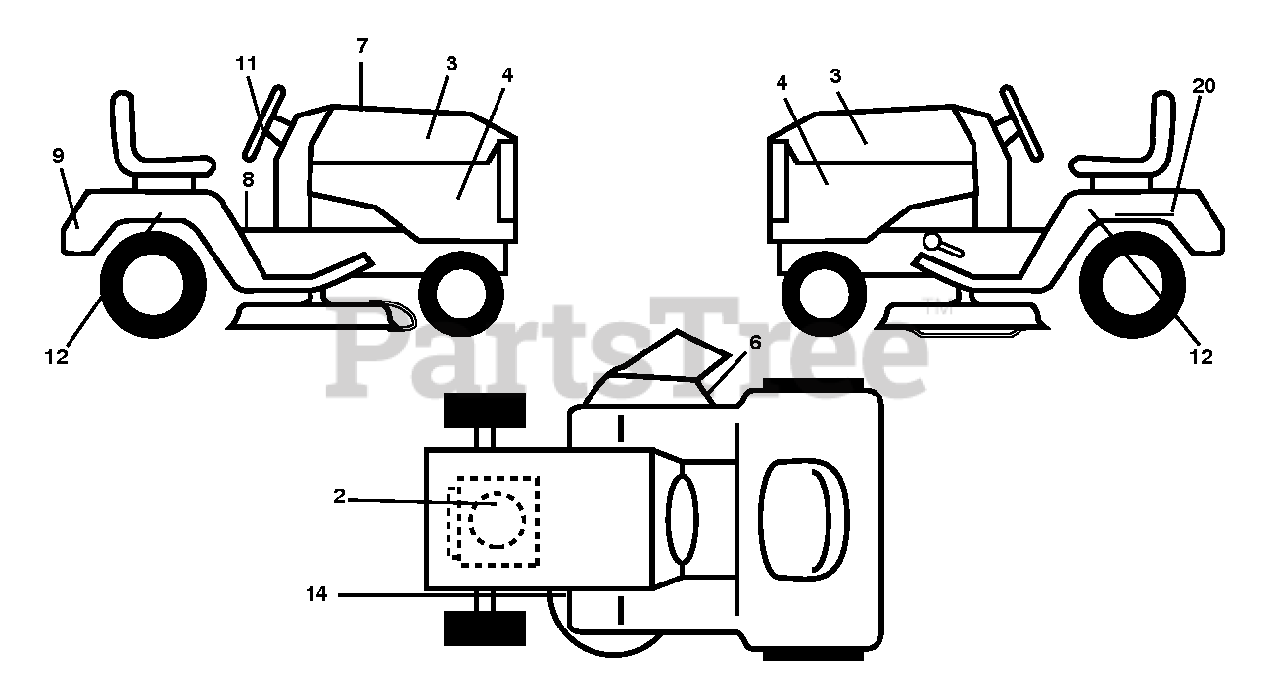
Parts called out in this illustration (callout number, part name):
2	DECAL.ENGINE.B&S.(278443)
3	DECAL.HOOD.POULAN.PRO.SET
6	DECAL.MOWER.WARN.KEEP.HAND.AWY
8	DECAL.FENDER.WARNING.ENGLISH
9	DECAL.REAR.FNDR.LOGO.POULAN.PR
11	DECAL.STEER.WHEEL.POULAN.PRO
14	DECAL.V-BELT.SCH.42/46"MEC/ELE
20	DECAL BTRY SYMBOLS
